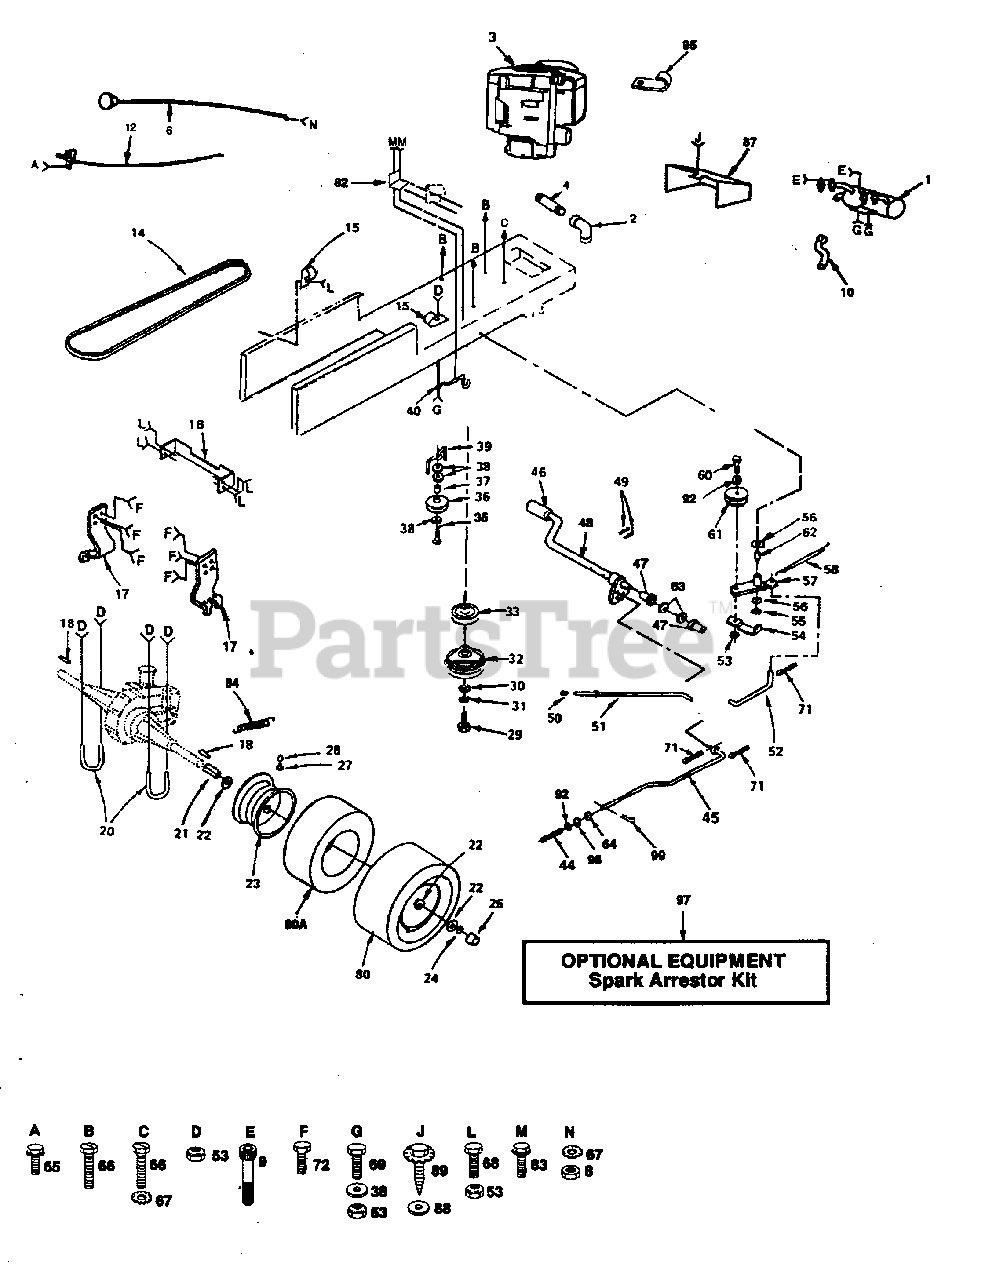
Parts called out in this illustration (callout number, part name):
2	Elbow, STD 90 3/8-18NPT
6	Control, Choke
8	Nut, Fin Hex 3/8-24 UNF
9	Screw, Hex Socket 5/16-18 x 3/4
12	Control, Throttle
14	V-Belt, Drive
15	Clip
16	Bracket, Mounting, Hydro T/A
17	Bracket, Transaxle
18	Key, Square 1/4 x 2
20	U-Bolt, 3/8-16 x 2-3/4
21	Spacer, Split
22	Washer 1-1/32 x 1-5/8 x 16 Ga,
23	Rim, Rear
30	Washer 1-1/2 OD X 15/32 ID X .250
31	Washer, Lock 7/16
32	Clutch, Electric
33	Pulley, Engine
35	Bolt, Hex 3/8-16 x 2-3/4
36	Idler, Flat
37	Spacer
38	Washer 13/32 x 13/16 x 12 Ga.
40	Keeper, Belt Engine Lh Lt
42	Belt, Keeper, Engine R.H.
44	Spring, Rod, Brake
46	Cover, Pedal
47	Bearing, Nylon
48	Shaft, Foot Pedal, Asm.
49	Pin, Roll 3/16 x 1
51	Rod, Brake, Park
52	Link, Clutch
53	Locknut, 3/8-16
54	Retainer, Belt
56	Washer, Hardened
57	Arm, Asm, Idler
58	Spring, Return, Clutch
60	Bolt, Hex, 3/8-16 x 1-1/2
61	Idler, V. Grove
63	Washer, 21/32 x 1 x 16 Ga.
64	Nut
65	Screw, Hex Thread Cut 1/4-20 x 5/8
66	Screw. Thdrol 3/8-16 x 1-1/2
67	Washer, Lock Ext Tooth 3/8
68	Bolt, Hex 3/8-16 x 3/4
69	Bolt, Hex 3/8-16 x 1
71	Pin, Cotter, 1/8 x 3/4
72	Screw, Hex, Thdrol 3/8-16 X 3/4
80	Tire
82	Bracket, Switch
83	Screw, Tap. Hex Hd. #10-24 x 1/2 Type T
84	Spring, Brake Return
89	Screw Spiderlock Hex Hd #8 x 1/2
92	Washer, 13/32 X 13/16 X 16 Ga.
95	Clamp Muffler
97	Spark Arrestor
98	Nut, Hex Jam 3/8 X 16 UNC
99	Clip, Hairpin
